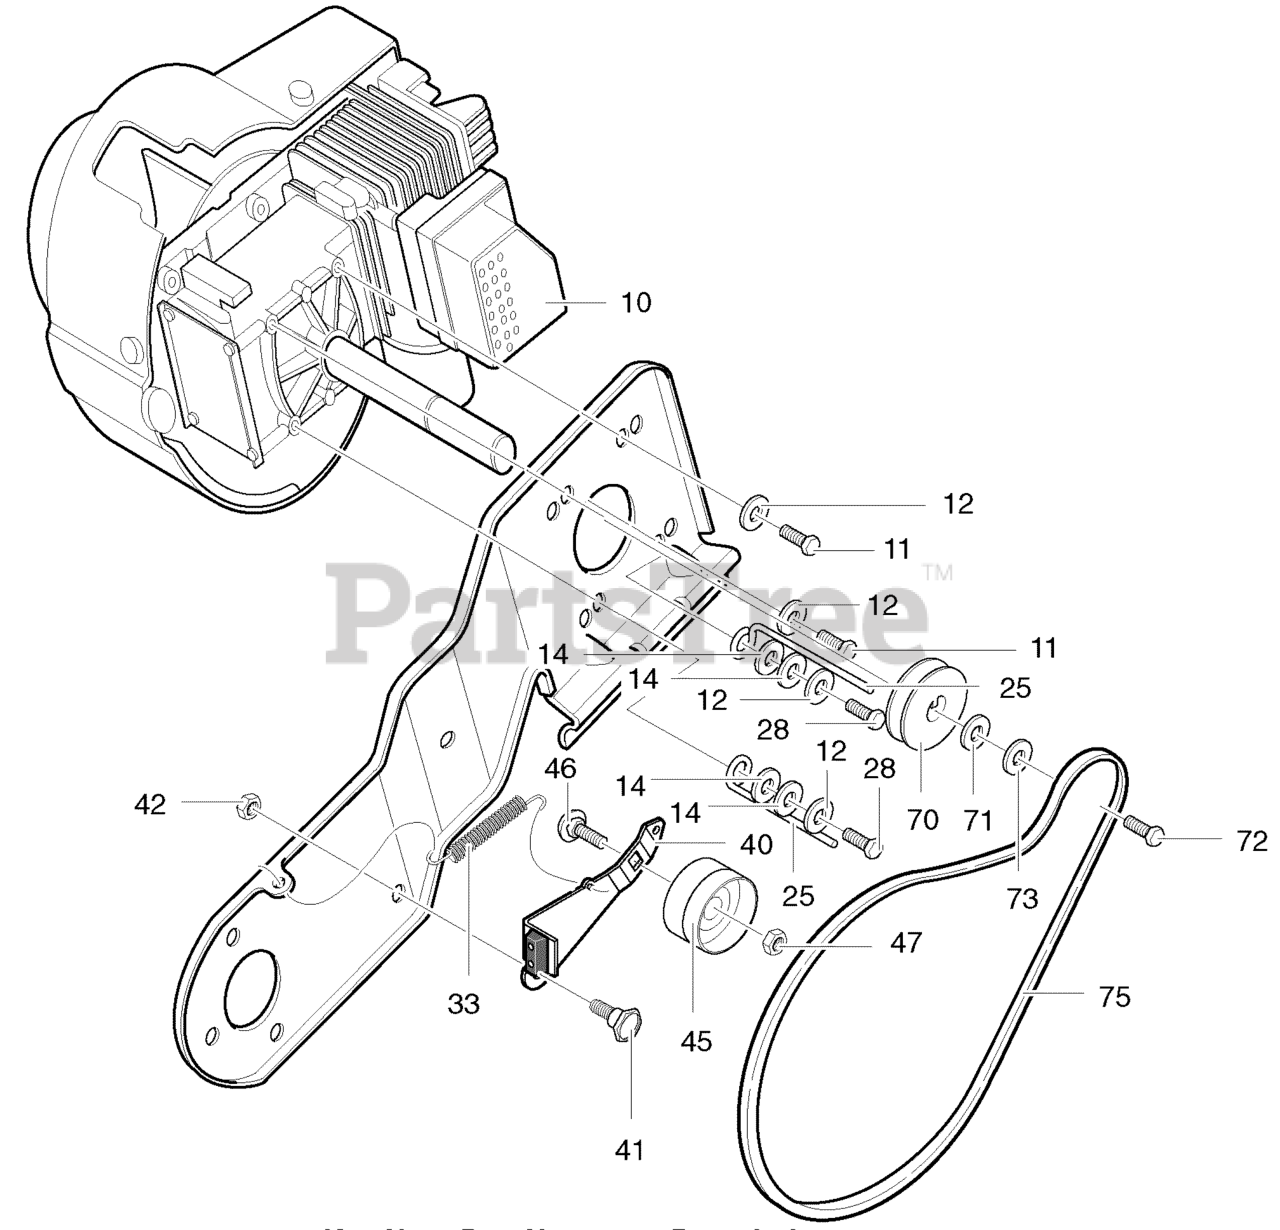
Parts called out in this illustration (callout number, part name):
10	ENGINE
11	SCREW, 5/16-18 X.75
14	WASHER, FLAT
25	GUIDE, BELT
33	SPRING, IDLER BRAKE
40	ASSY, IDLER BRAKE ARM
42	NUT, 5/16-18
45	PULLEY, IDLER
46	BOLT, CARRIAGE
70	PULLEY, ENGINE
71	WASHER, BELLEVILLE
72	SCREW, 5/16-24X.75
73	WASHER, SPLTLK
75	BELT V 3L 34.8"
